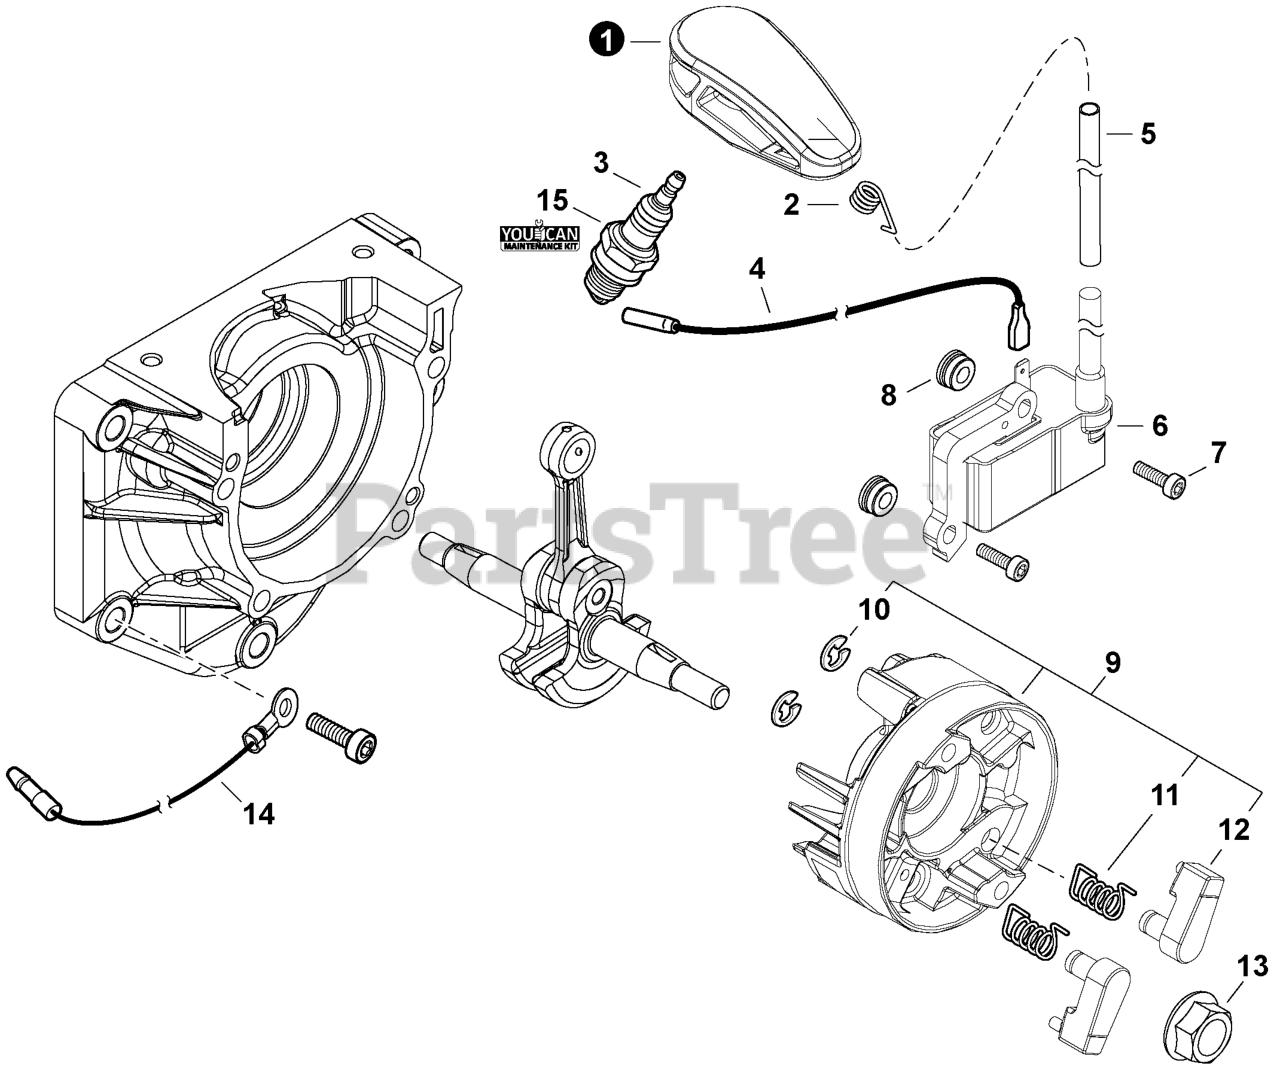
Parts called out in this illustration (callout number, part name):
1	CAP, SPARK PLUG
2	TERMINAL, SPARK PLUG
3	SPARK PLUG - CMR7H
5	TUBE, INSULATOR
6	COIL, IGNITION
7	BOLT 4x20
8	COLLAR 4
9	FLYWHEEL
11	SPRING, RETURN
12	PAWL, STARTER
13	NUT, FLANGE 10x1.25
15	TUNE-UP KIT - YOUCANT
